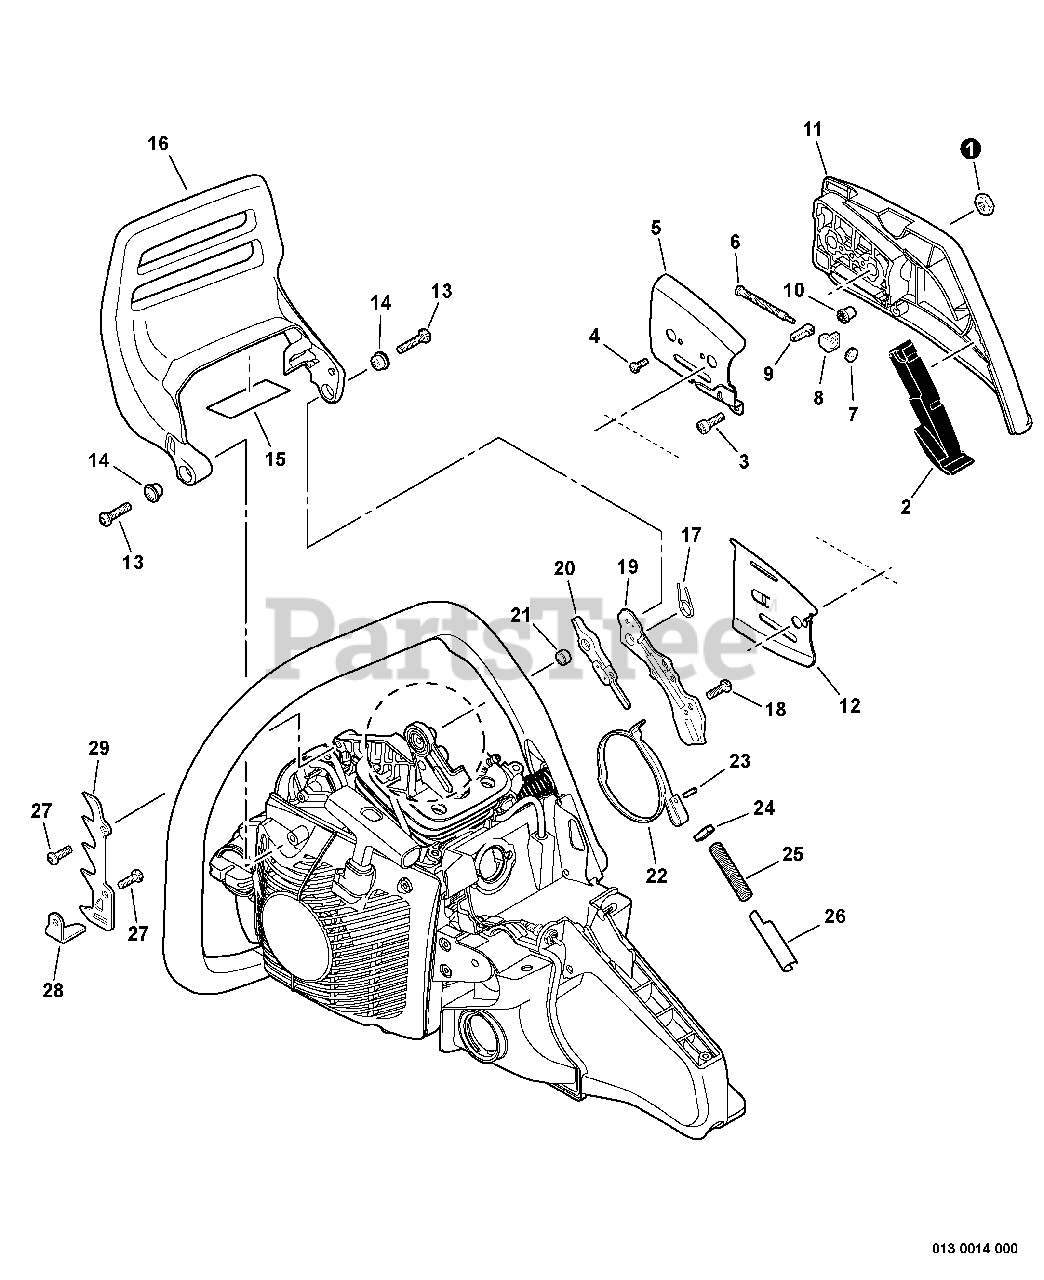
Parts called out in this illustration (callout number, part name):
1	NUT - 8
2	CUSHION
3	SCREW - 4X12
4	SCREW - 3X6
5	PLATE, GUIDE - OUTER
6	SCREW, TENSIONER
7	GEAR - BEVEL
8	COLLAR - 8
9	TENSIONER, CHAIN
10	GEAR - PINION
11	GUARD, SPROCKET
12	PLATE, GUIDE - INNER
13	SCREW - 5X16
15	DEFLECTOR, HEAT
16	LEVER, BRAKE
18	SCREW - 5X16
19	COVER, BRAKE
20	CONNECTOR, BRAKE
22	BAND, BRAKE
26	GUIDE, SPRING
27	SCREW - 5X16
28	CATCHER, CHAIN
29	SPIKE
